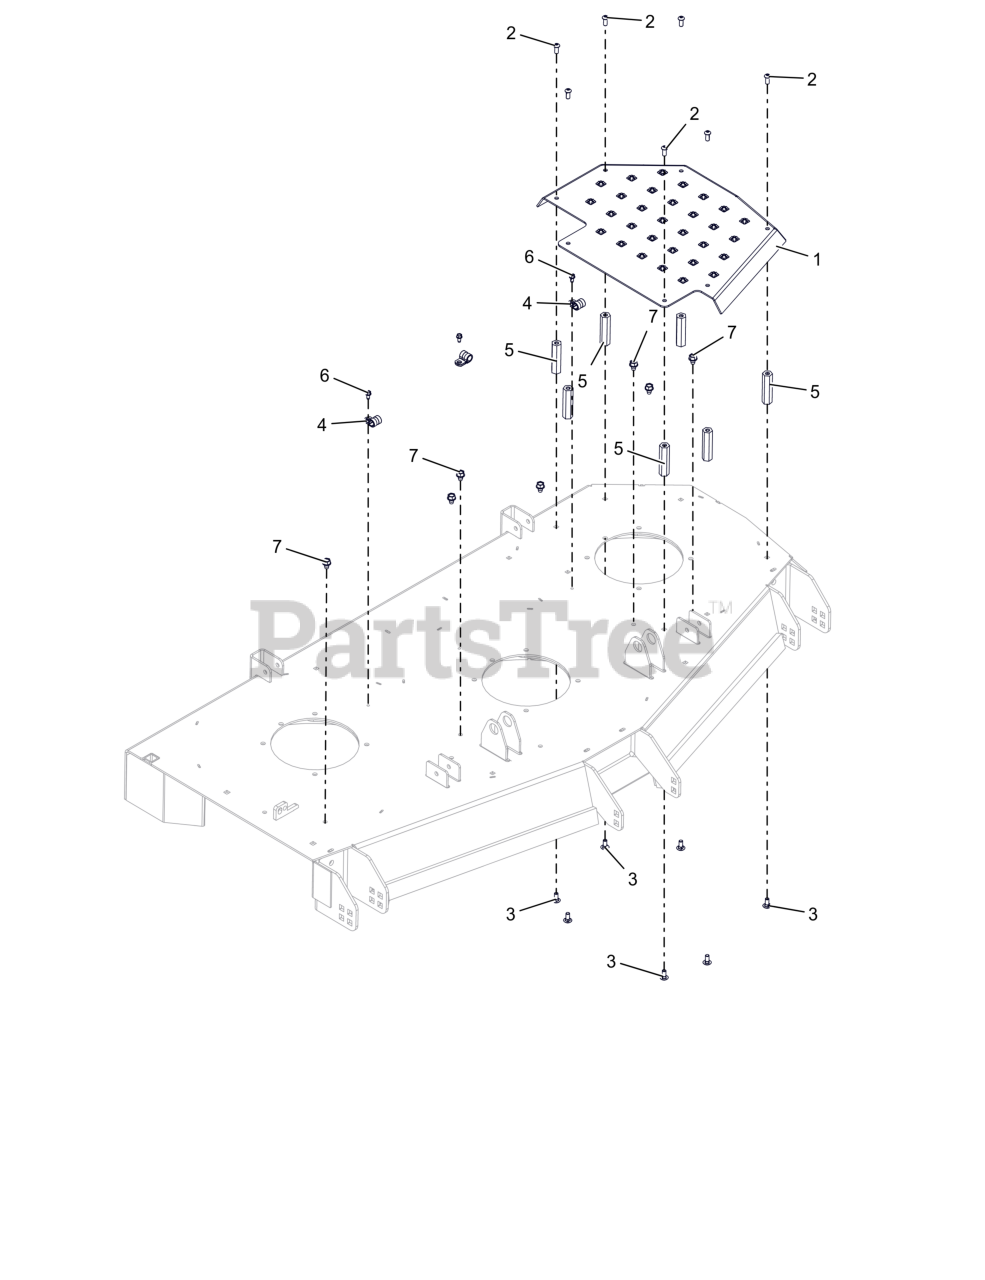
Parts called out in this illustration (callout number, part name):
1	PLATFORM, WLDMT 60 SD DECK STEP (RED)
2	SCR-SKH .31-18X.75 BTNHD YWZC
3	BTL,RHSN .313-18 X 0.75 G5 ZCC LT
4	CLAMP, CUSHIONED STEEL
5	NUT, COUPLING .31-18 X 3.00
6	SCR-TAP .25-20X.50 HWH ZCC
7	SCR,TAP .375-16X.50 HWH TR ZCC
